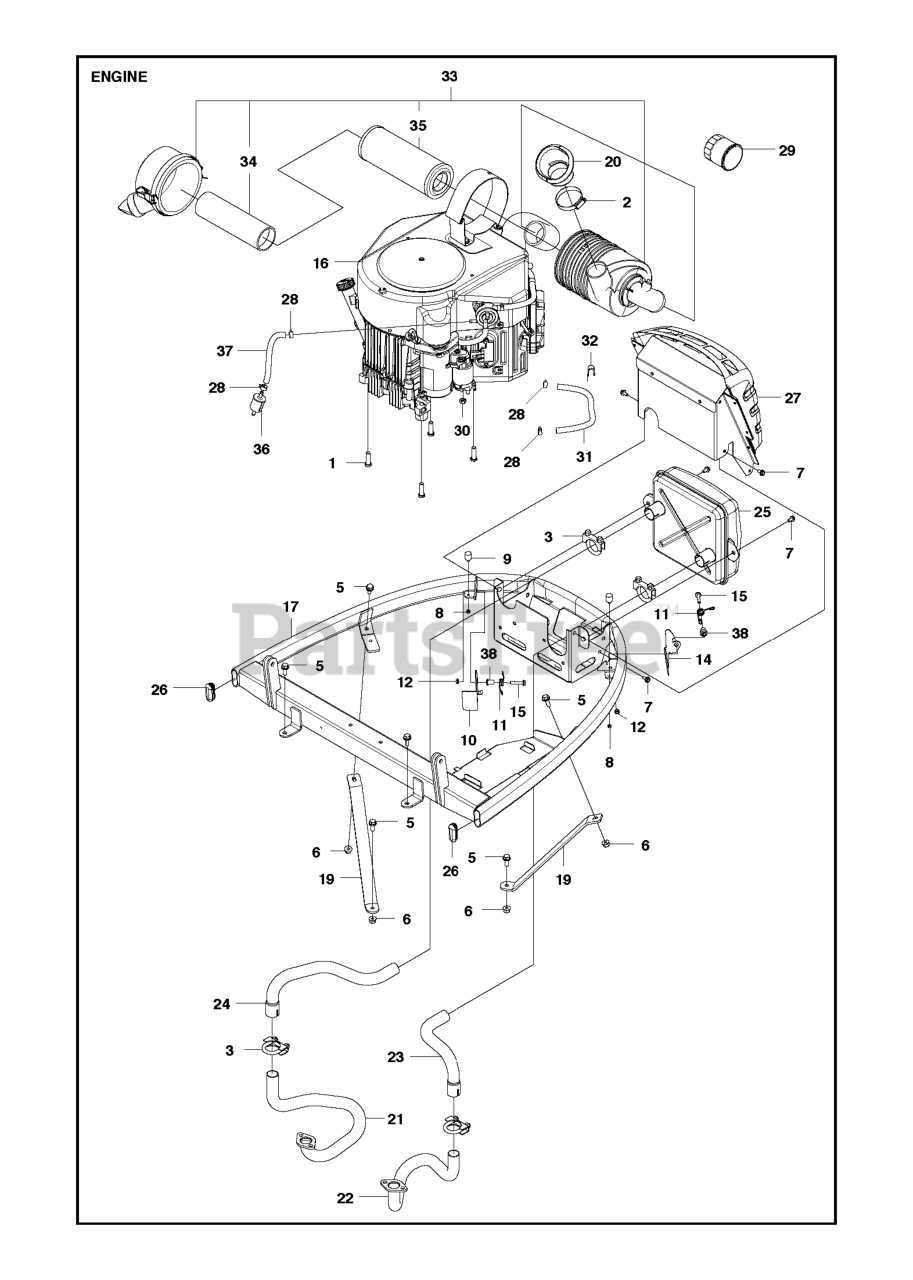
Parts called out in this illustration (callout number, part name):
3	CLAMP
5	SCREW EHHFM
6	NUT FLANGE
7	BOLT
8	LOCKNUT M5
12	LOCKNUT M6
29	OIL FILTERS
30	NUT
32	HOSE CLAMP
